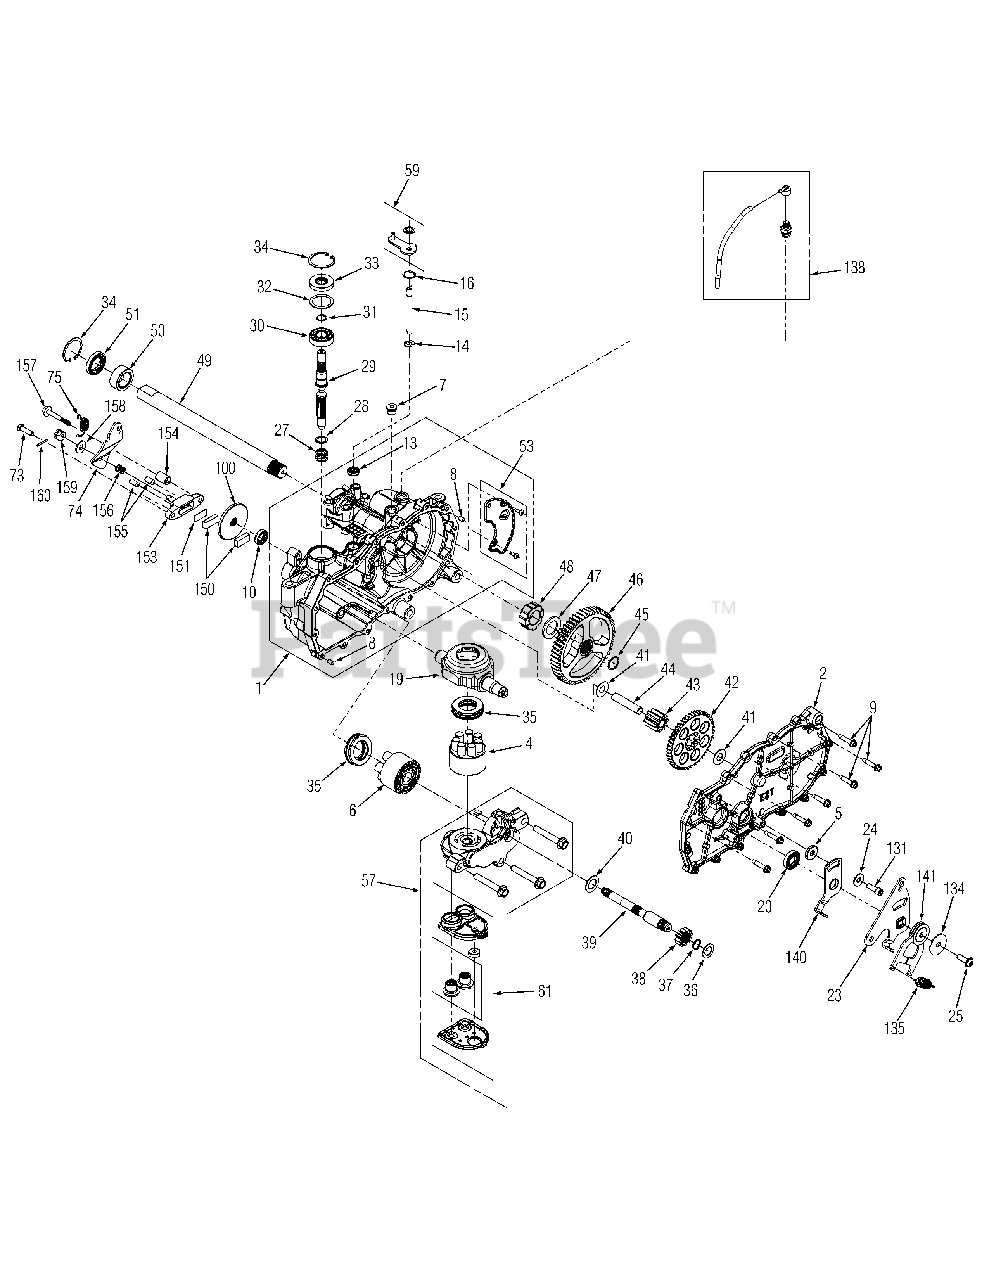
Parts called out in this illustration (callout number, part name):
1	Housing Assembly, Main RH
2	Side Assembly, RH
4	Block Kit - 7 Piston
5	Spacer, .32 x 1.005 x .179
6	Block Assembly, Cylinder
7	Plug, Straight Thread
9	Screw, Hex Flange
10	Seal, Oil
13	Seal, Lip
14	Ring, Retaining, .375 Ext.
15	Rod, Bypass
16	Ring, Retaining, .75 Int.
19	Swashplate, Trunnion
20	Seal, Lip
23	Arm, Control
24	Washer, Flat, .34 x .88 x.06
25	Screw, 5/16-24 x 1.0
27	Spring, Block
28	Washer, Thrust
29	Shaft, Input
30	Bearing, Ball
31	Ring, Retaining
33	Seal, Lip
34	Ring, Retaining
35	Bearing, Thrust
36	Washer, Flat, 5/8 x 1.0 x .05
37	Ring, Retaining
38	Gear, Pinion, 12T
39	Shaft, Motor
40	Washer, Motor Shaft
41	Washer, HT
42	Gear, 10T/49T
43	Gear, 10T Jackshaft
44	Pin, Jackshaft
45	Ring, Retaiining
46	Gear, Bull, 52T
47	Washer, 1.018 x 1.57 x .105
48	Bearing, Sleeve
49	Shaft, Axle
50	Bearing, Sleeve
51	Seal, Lip
53	Plate Kit, Expansion RH
57	Kit, Center Section RH
59	Kit, Bypass Arm RH
61	Filter Assembly
73	Screw, Hex
74	Arm, Brake
75	Spring, Brake
100	Rotor, Brake
131	Screw, Patch, 5/16-24 x 1
134	Washer, .343 x 1.5 x .062
135	Spring, Extension
138	Kit, Breather
140	Arm, Neutral, RH
141	Kit, Scissors Arm
150	Puck, Brake
151	Plate, Puck
153	Assembly, Brake Yoke
154	Spacer, Torsion Spring
155	Pin, Actuating
156	Spring, Brake
157	Bolt, Special Flange
158	Washer, Flat
159	Nut, Castle, 5/16-24
160	Pin, Cotter, 3/32 x .75
